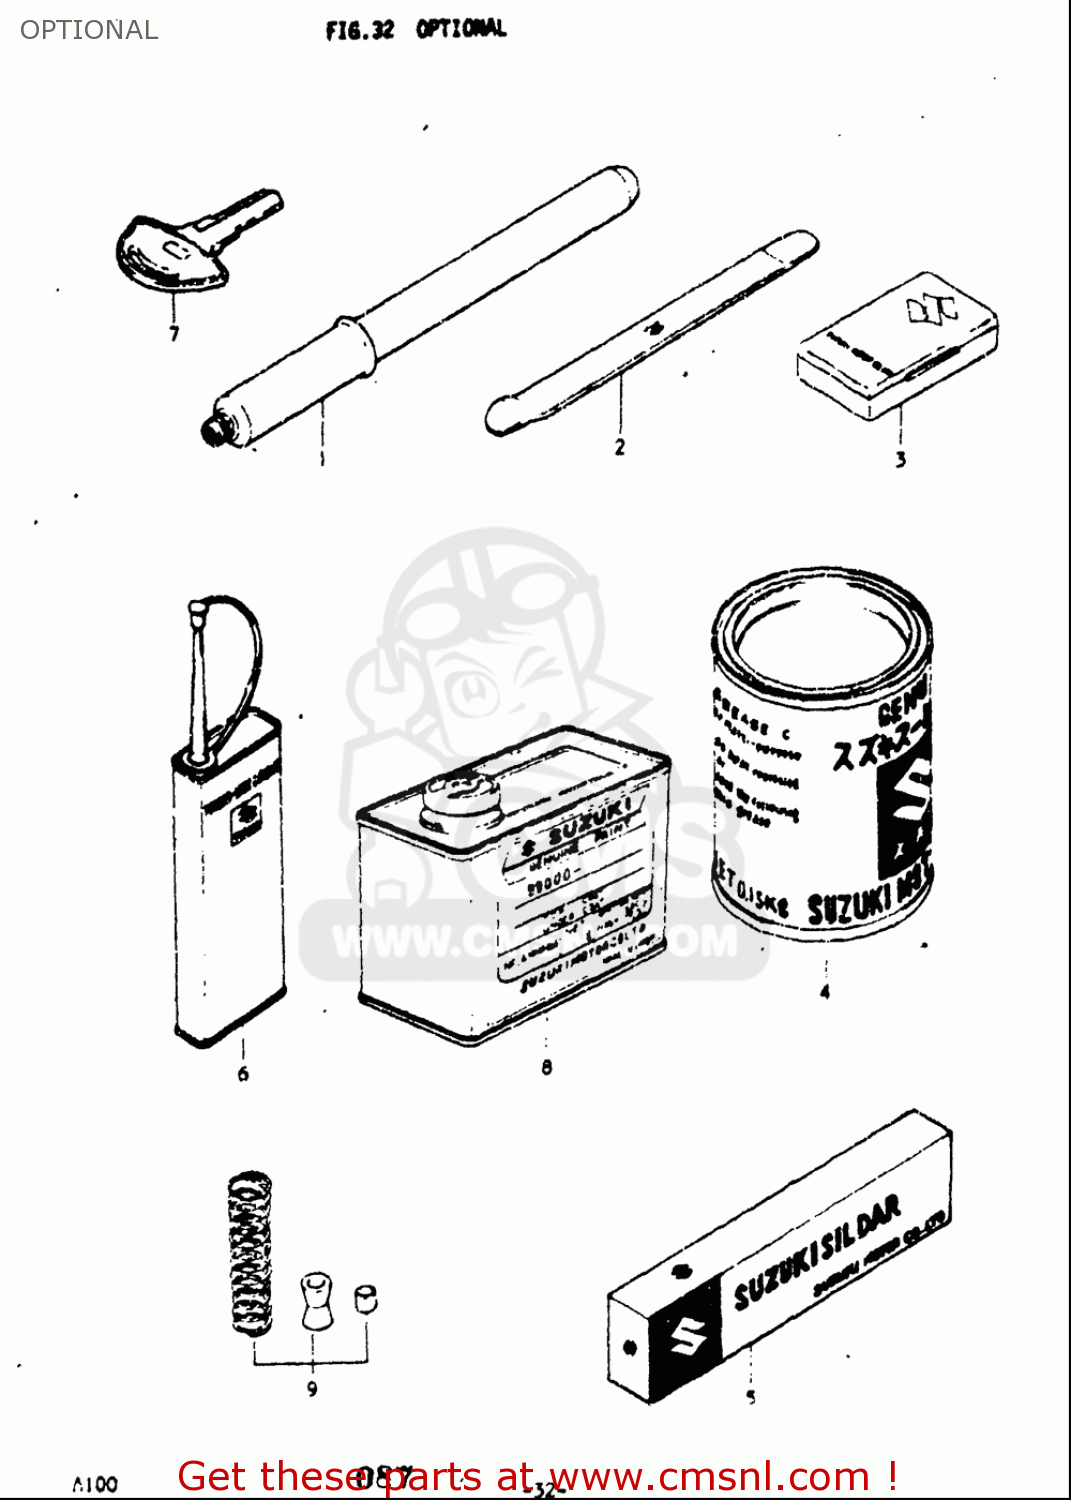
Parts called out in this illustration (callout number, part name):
2	LEVER,TIRE
4	GREASE(C)EP2 LITHIUM 150G
6	THREAD LOCK NO.1401 CLEAR 200G
7	KEY,BLANK
